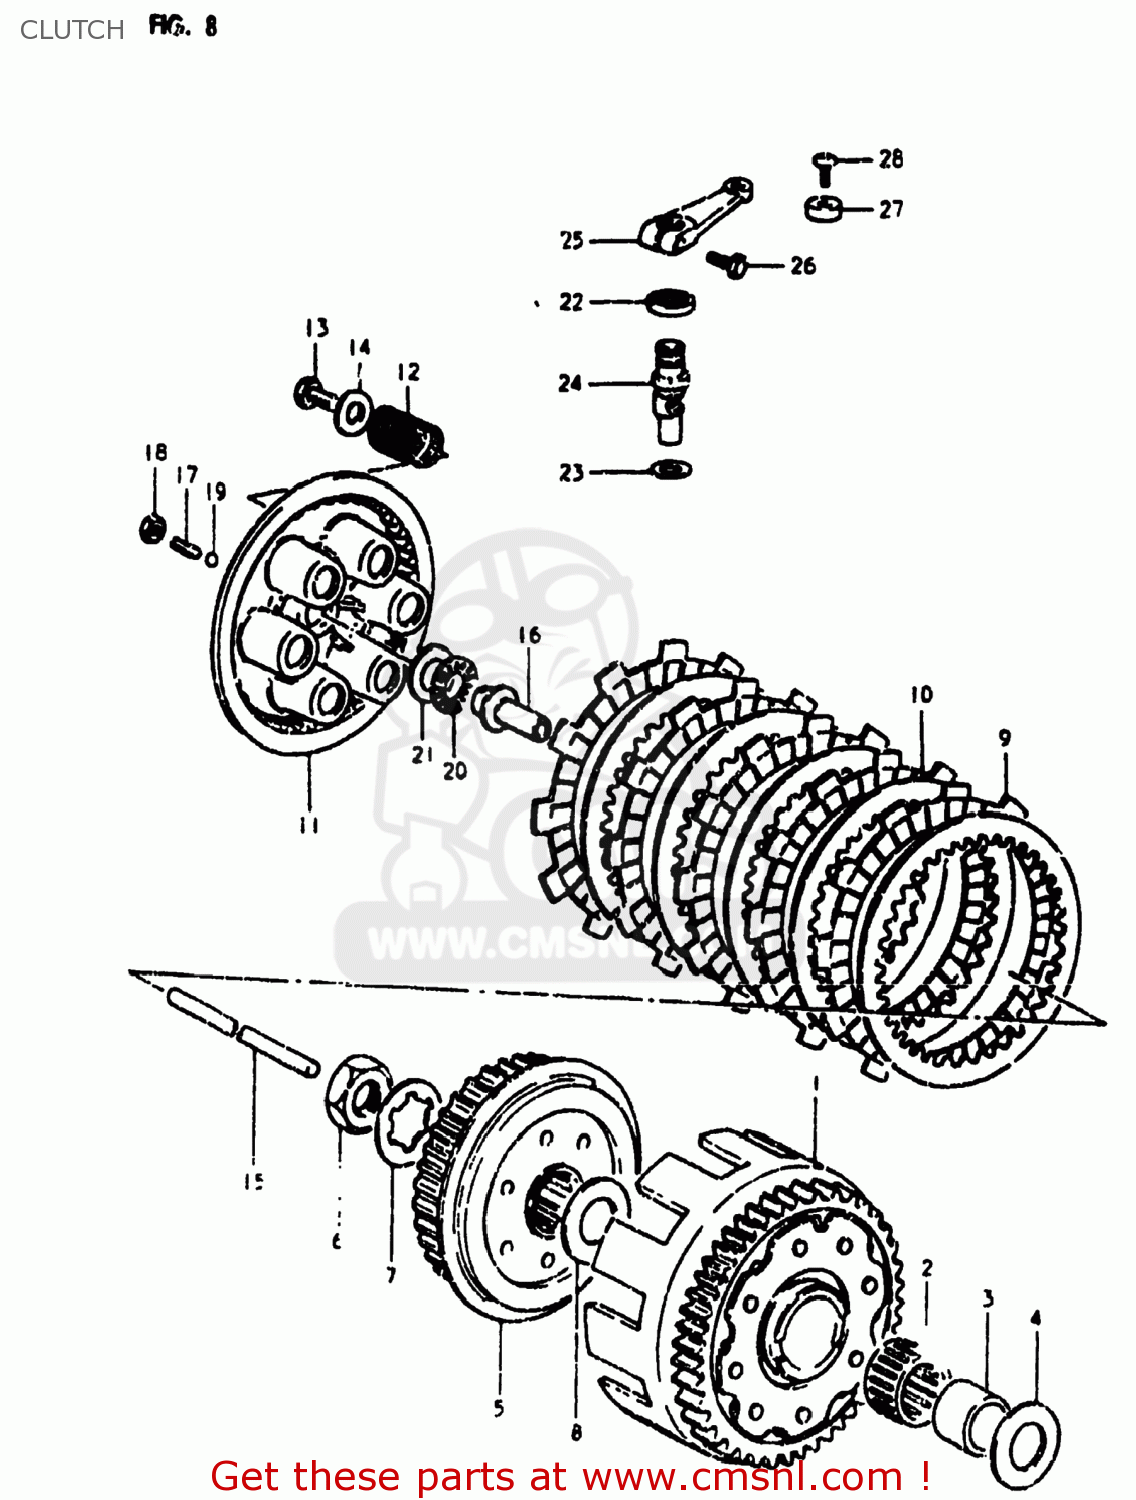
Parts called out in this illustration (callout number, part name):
1	GEAR ASSEMBLY,PRIMARY DRIVE
2	BEARING(30X35X19.8)
3	SPACER
4	WASHER
5	HUB,CLUTCH SLEEVE
6	NUT
7	WASHER,LOCK
8	WASHER
9	PLATE,CLUTCH DRIVE (MCA)
10	PLATE,CLUTCH DRIVEN (NAS)
11	DISC,CLUTCH PRESSURE
12	SPRING
13	BOLT, UPPER
14	WASHER
15	ROD,CLUTCH PUSH
16	PIECE,CLUTCH PUSH
17	SCREW
18	NUT 6MM
19	BALL
20	BEARING(15X28X2)
21	WASHER
22	OIL SEAL
23	WASHER (14.2X22X1)
24	SHAFT,CLUTCH RELEASE C
25	ARM,CLUTCH RELEASE
26	BOLT
27	GUIDE,CLUTCH CABLE
28	SCREW
